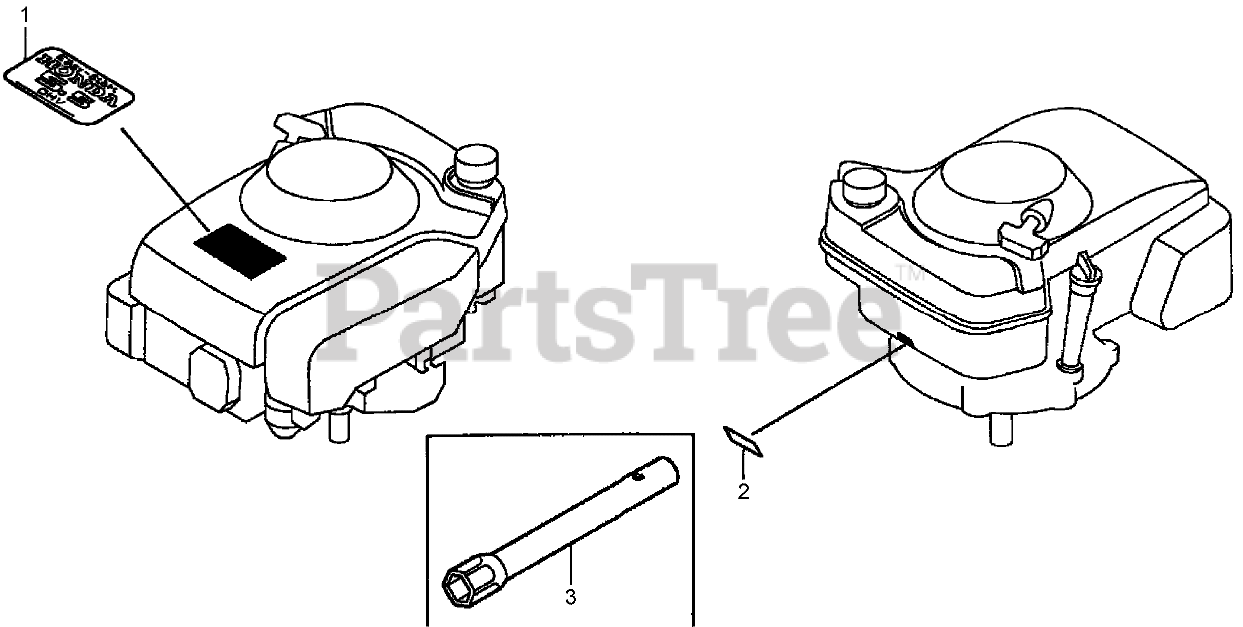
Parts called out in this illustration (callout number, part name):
1	EMBLEM (5.5)
2	MARK-TYPE (T1AH)
3	Wrench-Box (P21)
